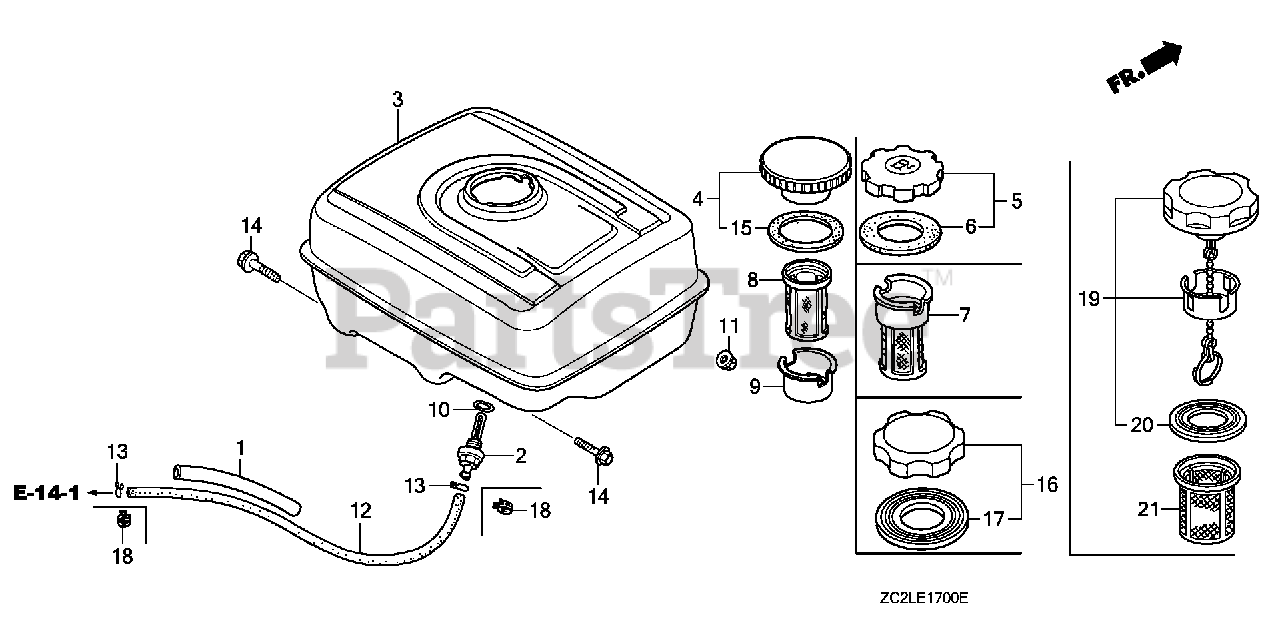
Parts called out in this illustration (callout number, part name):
1	RUBBER, SUPPORTER (107MM)
2	JOINT, FUEL TANK (NOT AVAILABLE)
2	JOINT, FUEL TANK
3	TANK, FUEL *R280* (POWER RED)
5	CAP, FUEL FILLER (BLACK)
6	GASKET, FUEL FILLER CAP (39X58X3)
7	FILTER, FUEL
10	O-RING (14MM) (ARAI)
10	O-RING (14MM) (NOK)
11	NUT, FLANGE (8MM)
12	BULK HOSE, FUEL (4.5X3000) (4.5X235)
13	CLIP, TUBE (B8)
14	BOLT, FLANGE (8X25)
